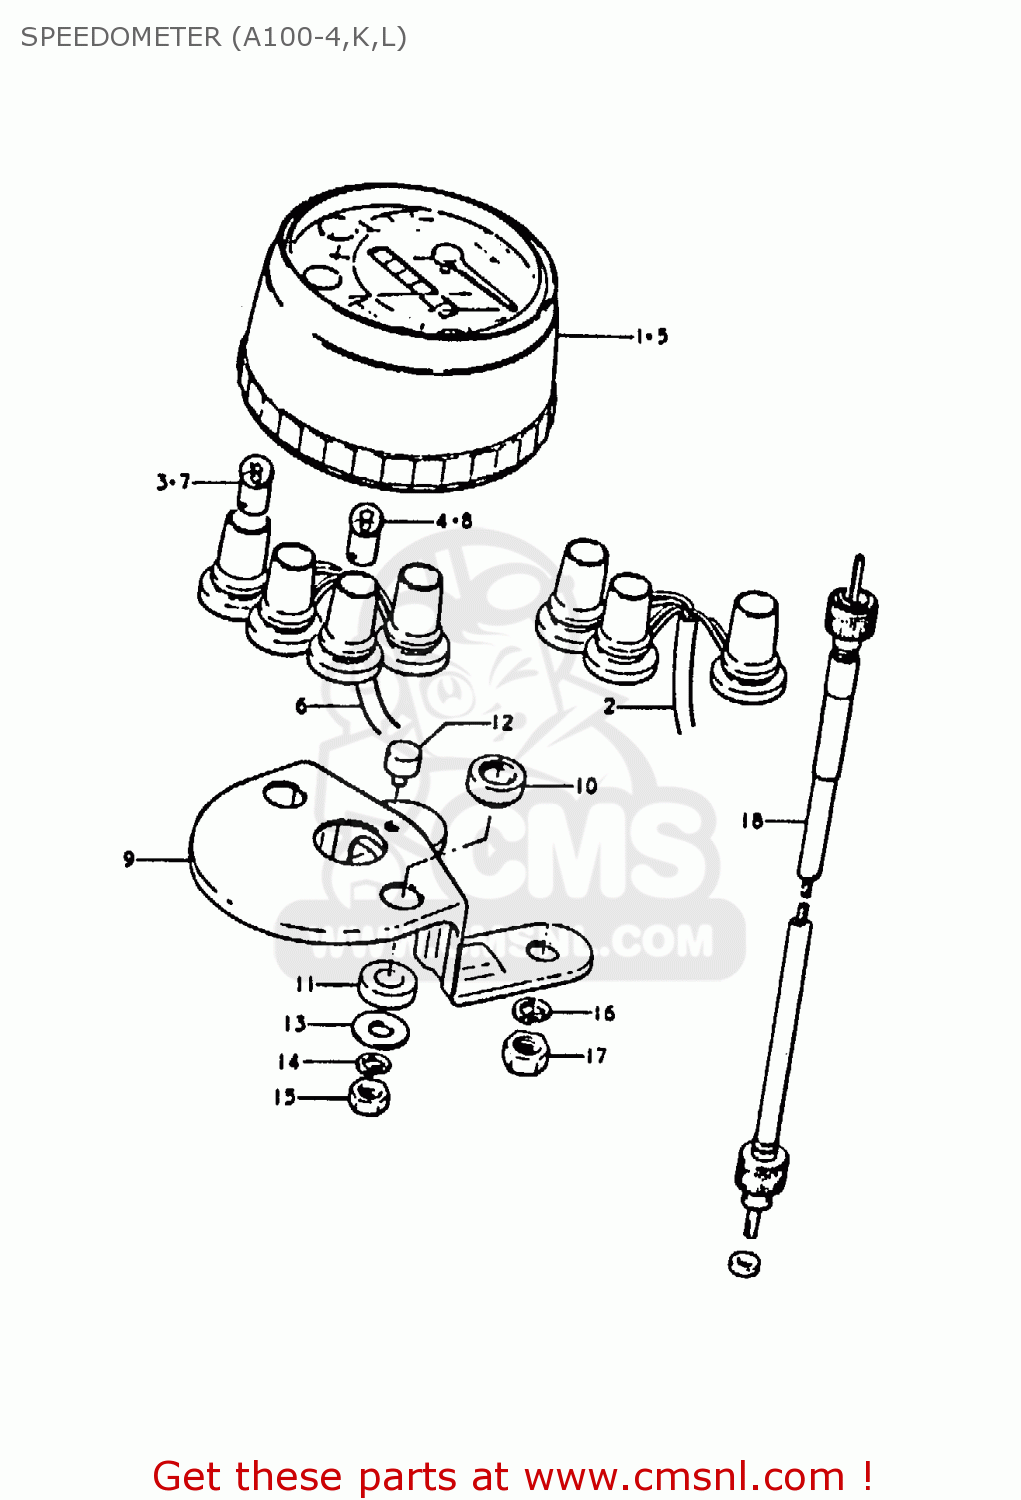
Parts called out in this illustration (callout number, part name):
1	SPEEDOMETER ASSY
2	SOCKET,SPEEDOMETER
3	BULB(6V/3W)
4	BULB(6V1.7W,STANLEY,A61A)
5	SPEEDOMETER ASSEMBLY
6	SOCKET,SPEEDOMETER
7	BULB(6V/3W)
8	BULB(6V1.7W,STANLEY,A61A)
9	BRACKET,SPEEDOMETER
10	CUSHION,METER
11	CUSHION
12	CUSHION,METER
13	WASHER(5.5X16X1.5)
14	LOCK WASHER
15	NUT
16	LOCK WASHER
17	NUT
18	CABLE ASSEMBLY,SPEEDOMETER
